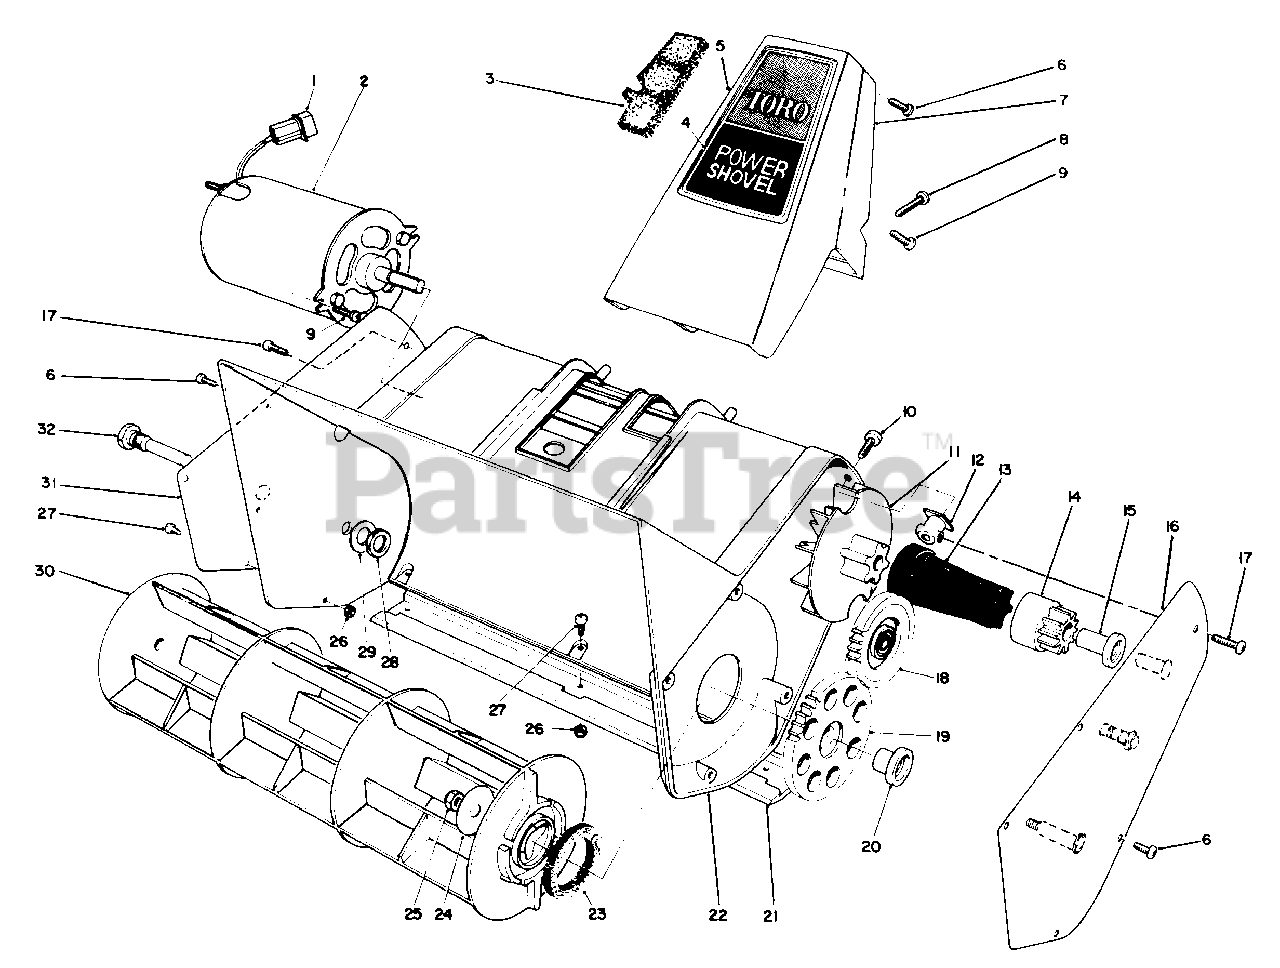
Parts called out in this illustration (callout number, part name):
1	Pin-Housing
2	Motor
3	Filter-Foam
4	Decal-Handle Support
5	Handle Support-Front
6	Screw-Pan Head
7	Handle Support-Back
8	Screw-Pan Head
9	Screw-Pan Head
10	Screw-Phillips Head
12	Block-Mounting
13	Coupling-Drive
14	Drive Gear (Incl. Ref. #15)
15	Bushing-Drive Gear
16	Gear-Carrier
17	Screw-Pan Head
18	Idler Gear Assembly
19	Rotor Gear Assembly (Incl. Ref. #20)
20	Bushing-Rotor
21	Scraper
22	Housing
23	Washer-Felt
24	Washer-Rotor
26	Locknut-Thin
27	Screw-Pan Head
28	Nut-Lock
29	Flat-Washer
31	Cover-Right Side
32	Pin-Rotor
